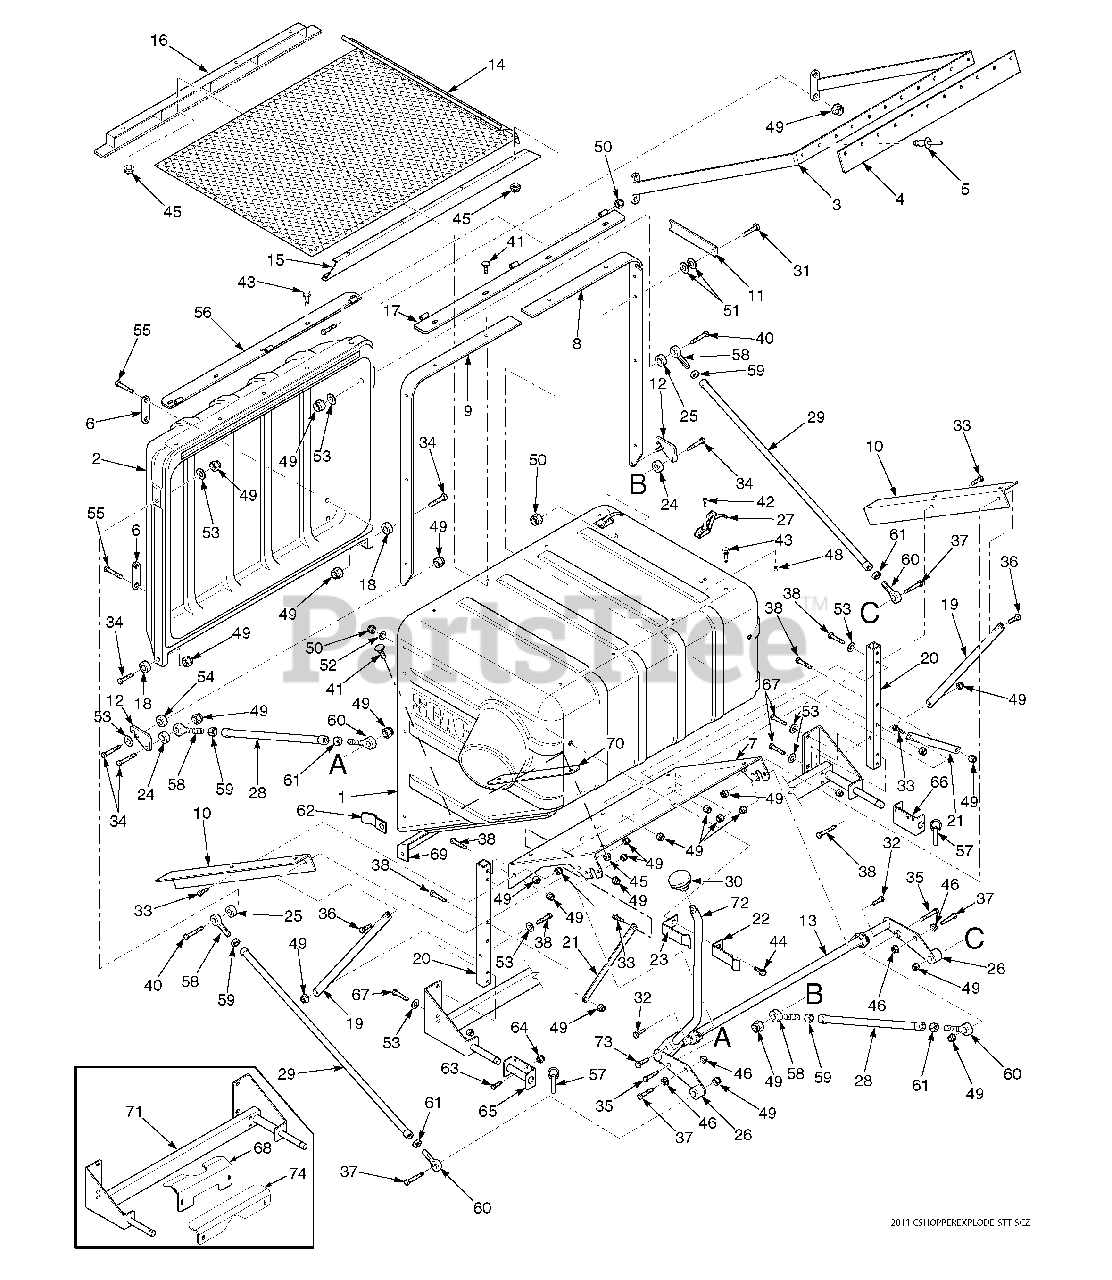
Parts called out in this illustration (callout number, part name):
1	Hopper, GC-STT-CS
2	Door, GC-CS
3	Sweeper Weldment, GC-CS
4	Pad, Rubber
5	Pop Rivet, 3/16 x .652
6	Plate, Stiffener
7	Support Frame, Hopper
8	Hinge Bracket, LH
9	Hinge Bracket, RH
10	Bracket, Hopper Support
11	Latch, Door Prop
12	Plate, Latch
13	Bellcrank Weldment, Lever
14	Debris Screen Weldment
15	Screen Support Weldment, Rear
16	Screen Support Weldment, Front
17	Hinge Weldment, Hopper
18	Spacer
19	Brace Stiffener, Short
20	Tube, Upright
21	Brace, Engine Mount
22	Latch, Dump Rod Inner
23	Latch, Dump Rod Outer
24	Spacer
25	Spacer
26	Spacer
27	Latch, Hood
28	Linkage Assembly, Lower
29	Linkage Assembly, Upper
31	Bolt, Hex Head 5/16-18 x 1-1/4"
32	Bolt, Hex Head 3/8-16 x 3/4"
33	Bolt, Hex Head 3/8-16 x 1"
34	Bolt, Hex Head 3/8-16 x 1-1/2"
35	Bolt, Hex Head 3/8-16 x 1-3/4"
36	Bolt, Hex Head 3/8-16 x 1-1/4"
37	Bolt, Hex Head 3/8-16 x 2"
38	Bolt, Hex Head 3/8-16 x 2-1/4"
39	Bolt, Hex Head 5/16-18 x 3-1/2"
40	Bolt, Hex Head 3/8-16 x 3-1/2"
41	Bolt, Carriage 5/16-18 x 1"
42	Screw, #10-32 x 1/2"
43	Cap Screw, 5/16-18 x 3/4" Serr. Flan.
44	Cap Screw, 5/16-18 x 1" Serr. Flan.
45	Nut, 5/16-18 Serrated Flange
46	Nut, 3/8-16 Serrated Flange
47	Nut, 3/8-16 UNC Jam
48	Nut, #10-32 Elastic Stop
49	Nut, 3/8-16 Elastic Stop
50	Nut, 5/16-18 Elastic Stop
51	Washer, Special Wave
52	Washer, 5/16-.375 x .875 x .083 Flat
53	Washer, 3/8-.931 x .938 x .105 Flat
54	Bushing, Hopper Latch GC-CS
55	Bolt, Hex Head 3/8-16 x 3"
56	Hinge Weldment, Door
58	Rod End Male, 3/8-24 LH Thread
59	Nut, 3/8-24 UNF LH Thread
60	Rod End Male, 3/8-24 RH Thread
61	Nut, 3/8-24 UNF RH Thread
62	Alignment Bracket, GC-CS
63	Bolt, Hex Head 3/8-16 x 1"
64	Nut, 3/8-16 Elastic Stop
65	Hitch Bracket Weldment
66	Hitch Bracket Weldment, Floating
67	Bolt, Hex Head 3/8-16 x 3-3/4"
68	Support Bracket, Catcher STT
69	Bracket, Lower Stiffener
70	Retainer Strip, Hopper
71	Frame Weldment
72	Rod, Dump Lever
73	Bolt, Hex Head 5/16-18 x 1-3/4"
74	Support Bracket, GC
